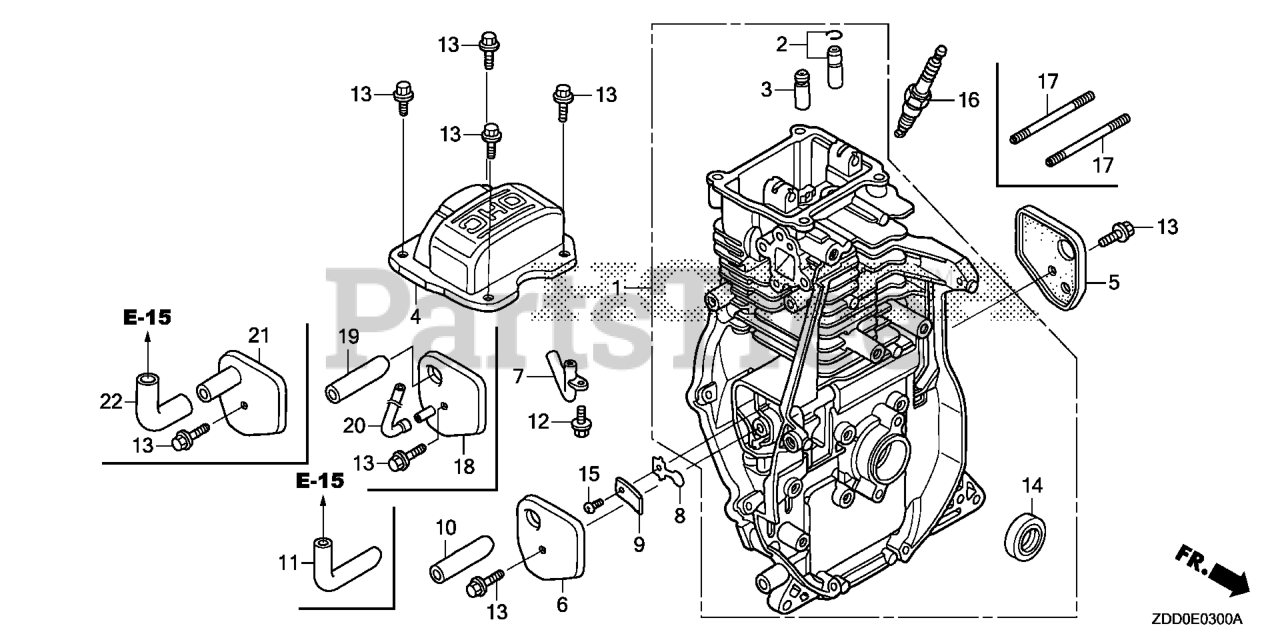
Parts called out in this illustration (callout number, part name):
1	CYLINDER ASSY.
4	COVER, HEAD
5	COVER A, BREATHER
6	COVER B, BREATHER
7	PIPE, BREATHER
8	VALVE, OIL OUTLET
9	PLATE, STOPPER
11	TUBE, BREATHER (BOMAG)
12	BOLT (4X10)
13	BOLT, FLANGE (6X14)
14	OIL SEAL (20X32X6)
15	SCREW, PAN (3X5)
16	SPARK PLUG (CR5HSB)
